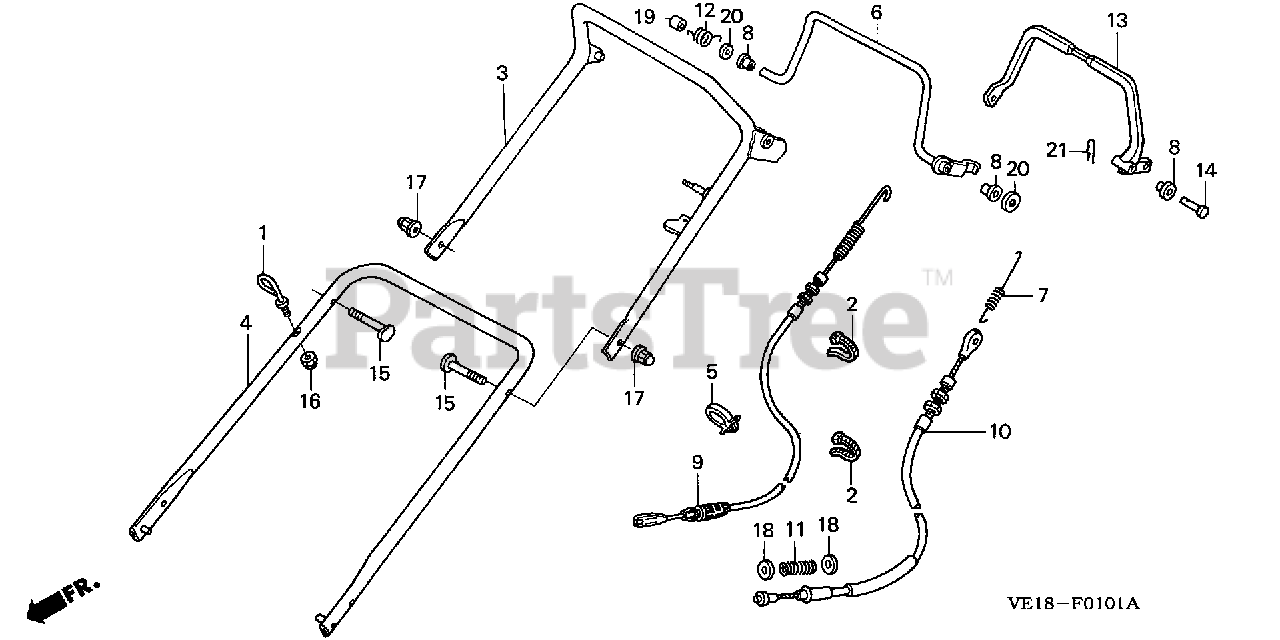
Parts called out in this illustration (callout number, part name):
1	GUIDE, ROPE
2	TIE, CABLE (157.5MM)
3	PIPE, HANDLE (UPPER) *NH105* (MAT BLACK)
4	HANDLE (LOWER) *NH105* (MAT BLACK)
5	CLIP, POWER STEERING SUCTION TUBE
6	LEVER, CLUTCH
7	SPRING, CLUTCH
8	BUSH, CLUTCH LEVER
9	CABLE, CLUTCH
10	CABLE, BRAKE
11	SPRING B, BRAKE
12	SPRING, R. STOP RETURN
13	LEVER, BRAKE *NH105* (MAT BLACK)
14	PIN, CLUTCH LEVER
15	BOLT, HANDLE HOLDER (8X36)
16	NUT, NYLON LOCK (6MM)
17	NUT, CAP (8MM)
18	WASHER, SPECIAL (6MM)
19	COLLAR (8X11X13.5)
20	WASHER, PLAIN (8MM)
21	PIN, LOCK (8MM)
